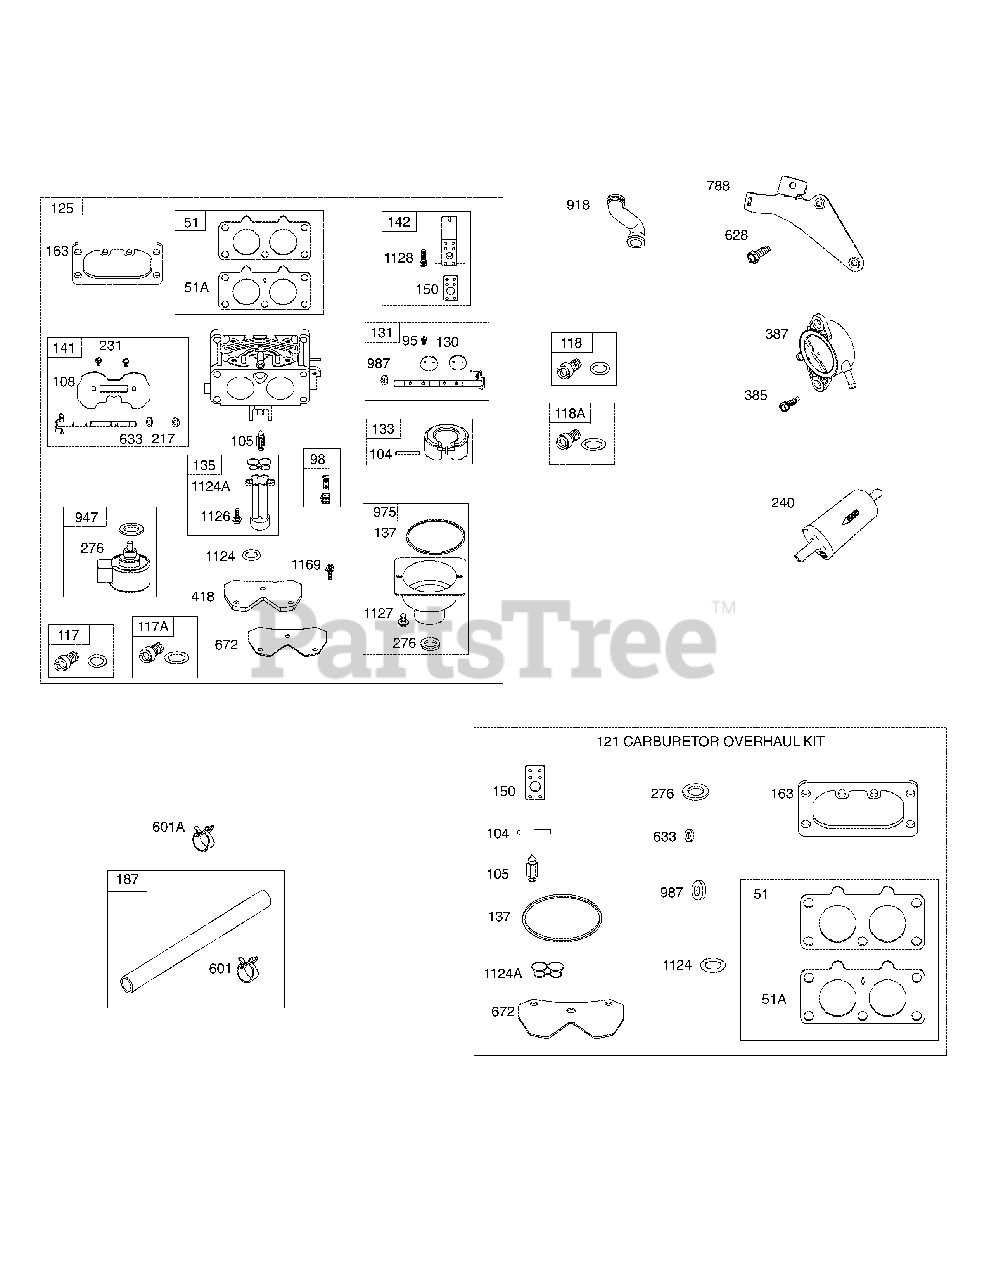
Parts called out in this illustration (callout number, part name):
1	Cylinder Assembly
2	Kit-Bushing/Seal (Magneto Side)
3	Oil Seal (Magneto Side)
4	EngineSump
5	Cylinder Head (Cylinder #1)
5A	Cylinder Head (Cylinder #2)
7	Cylinder Head Gasket
8	Breather Assembly
9	Breather Gasket
10	Screw (Breather Assembly)
11	Breather Tube
12	Crankcase Gasket
13	Screw (Cylinder Head)
15	Oil Drain Plug
16	Crankshaft
20	Oil Seal (PTO Side)
22	Screw (Crankcase Cover/Sump)
23	Flywheel
24	Flywheel Key
25	Piston Assembly (Standard)
25	Piston Assembly (.020" Oversize)
26	Ring Set (Standard)
26	Ring Set (.020" Oversize)
27	Piston Pin Lock
28	Piston Pin
29	Connecting Rod
32	Screw (Connecting Rod)
33	Exhaust Valve
34	Intake Valve
35	Valve Spring (Intake)
36	Valve Spring (Exhaust)
40	Valve Retainer
42	Valve Keeper
45	Valve Tappet
48	Short Block
50	Intake Manifold
51	Intake Gasket
51A	Intake Gasket
53	Stud (Carburetor)
54	Screw (Intake Manifold)
73	Rotating Screen
74	Screw (Rotating Screen)
75	Washer (Flywheel)
95	Screw (Throttle Valve)
98	Idle Speed Kit
104	Float Hinge Pin
105	Float Needle Valve
108	Choke Valve
117	Main Jet (Standard) (Left Jet)
117A	Main Jet (Standard) (Right Jet)
118	Main Jet (High Altitude) (Left Jet)
118A	Main Jet (High Altitude) (Right Jet)
121	Carburetor Overhaul Kit
125	Carburetor
130	Throttle Valve
131	Throttle Shaft Kit
133	Carburetor Float
135	Fuel Transfer Tube
137	Float Bowl Gasket
141	Choke Shaft Kit
142	Carburetor Nozzle
146	Timing Key
150	Nozzle Gasket
163	Air Cleaner Gasket
165	Nut (Ring Gear)
177	O-Ring Seal (Dipstick)
187	Fuel Line (Cut to Required Length)
188	Screw (Control Bracket)
192	Rocker Arm Adjuster
197	Screw (Back Plate)
209	Governor Spring (Yellow/Black)
211	Governed Idle Spring (Orange)
212	Throttle Link
216	Choke Link
217	Choke Return Spring
219	Governor Gear
220	Washer (Governor Gear)
221	Governor Cup
222	Control Bracket
227	Governor Control Lever
231	Screw (Choke Valve)
239	Oil Pressure Switch
240	Fuel Filter
250	Breather Retainer
252	Oil Collector
265	Casing Clamp
267	Screw (Casing Clamp)
276	Sealing Washer (Fuel Solenoid)
278	Washer (Governor Control Lever)
287	Screw (Dipstick Tube)
304	Blower Housing
305	Screw (Blower Housing)
305A	Screw (Blower Housing to Intake Elbow)
306	Cylinder Shield (Cylinder #2)
307	Screw (Cylinder Shield) (1.4-20 x 2.3)
309	Starter Motor
310	Screw (Starter Motor)
332	Nut (Flywheel)
333	Magneto Armature
334	Screw (Magneto Armature)
337	Spark Plug
358	Engine Gasket Set
385	Screw (Fuel Pump)
387	Fuel Pump
404	Washer (Governor Crank)
415	Plug (Oil Pressure Switch)
418	Carburetor Plate
431	Intake Elbow
445	Air Cleaner Cartridge Filter
447	Screw (Air Guide Cover) 10-24 x 7.16)
447A	Screw (Air Guide Cover)
467	Air Cleaner Knob
474	Alternator
501	Regulator
503	Starter Strap
505	Nut (Governor Control Lever)
510	Starter Drive
513	Drive Clutch
523	Dipstick
524	Dipstick Tube Seal
525	Dipstick Tube
526	Screw (Regulator)
544	Starter Armature
552	Governor Crank Bushing
552A	Governor Crank Bushing
562	Screw (Governor Control Lever)
573	Back Plate
579	Nut (Starter Cable)
601	Hose Clamp (Black)
601A	Hose Clamp (Green)
615	Governor Shaft Retainer
616	Governor Crank
617	O-Ring Seal (Intake Manifold) (Red)
628	Screw (Fuel Pump Bracket)
633	Choke Seal/Throttle Shaft
635	Spark Plug Boot
654	Nut (Carburetor)
668	Spacer (Rotating Screen)
668A	Spacer (Rotating Screen)
672	Carburetor Plate Gasket
691	Governor Shaft Seal
695	Screw (Ring Gear)
697	Screw (Drive Cap)
718	Locating Pin
741	Timing Gear
742	E-Ring Retainer (Governor Crank)
750	Screw (Oil Pump Cover)
783	Pinion Gear
788	Fuel Pump Bracket
789	Wiring Harness
798	Screw (Rocker Arm)
803	Starter Housing
847	Dipstick/Tube Assembly
851	Spark Plug Terminal
865	Air Guide Cover (Cylinder #1)
865A	Air Guide Cover (Valley)
868	Valve Seat
877	Alternator Wire/Connector
877A	Alternator Wire/Connector
883	Exhaust Gasket
914	Screw (Rocker Cover)
918	Vacuum Hose
943	O-Ring Seal (Oil Pump Cover)
947	Fuel Solenoid
965	Oil Pump Cover
967	Pre-Cleaner Filter
968	Air Cleaner Cover
975	Float Bowl
987	Throttle Shaft Seal
1005	Flywheel Fan
1013	Oil Filter Nipple
1017	Oil Pump Screen
1022	Rocker Cover Gasket
1023	Rocker Cover (Cylinder #1)
1023A	Rocker Cover (Cylinder #2)
1026	Push Rod (Exhaust)
1026A	Push Rod (Intake)
1027	Oil Filter
1029	Rocker Arm
1036	Emissions Label
1040	Trim Plate
1051	Retaining Ring (Starter Drive)
1058	Operator's Manual
1059	Screw/Washer Kit (Alternator)
1070	Screw (Flywheel Fan)
1090	Brush Retainer
1095	Valve Gasket Set
1100	Rocker Arm Pivot
1119	Screw (Alternator)
1124	O-Ring Seal (Fuel Transfer Tube)
1124A	O-Ring Seal (Fuel Transfer Tube)
1126	Screw (Fuel Transfer Tube)
1127	Screw (Fuel Bowl)
1128	Screw (Carburetor Nozzle)
1169	Screw (Carburetor Plate)
1329	Replacement Engine
